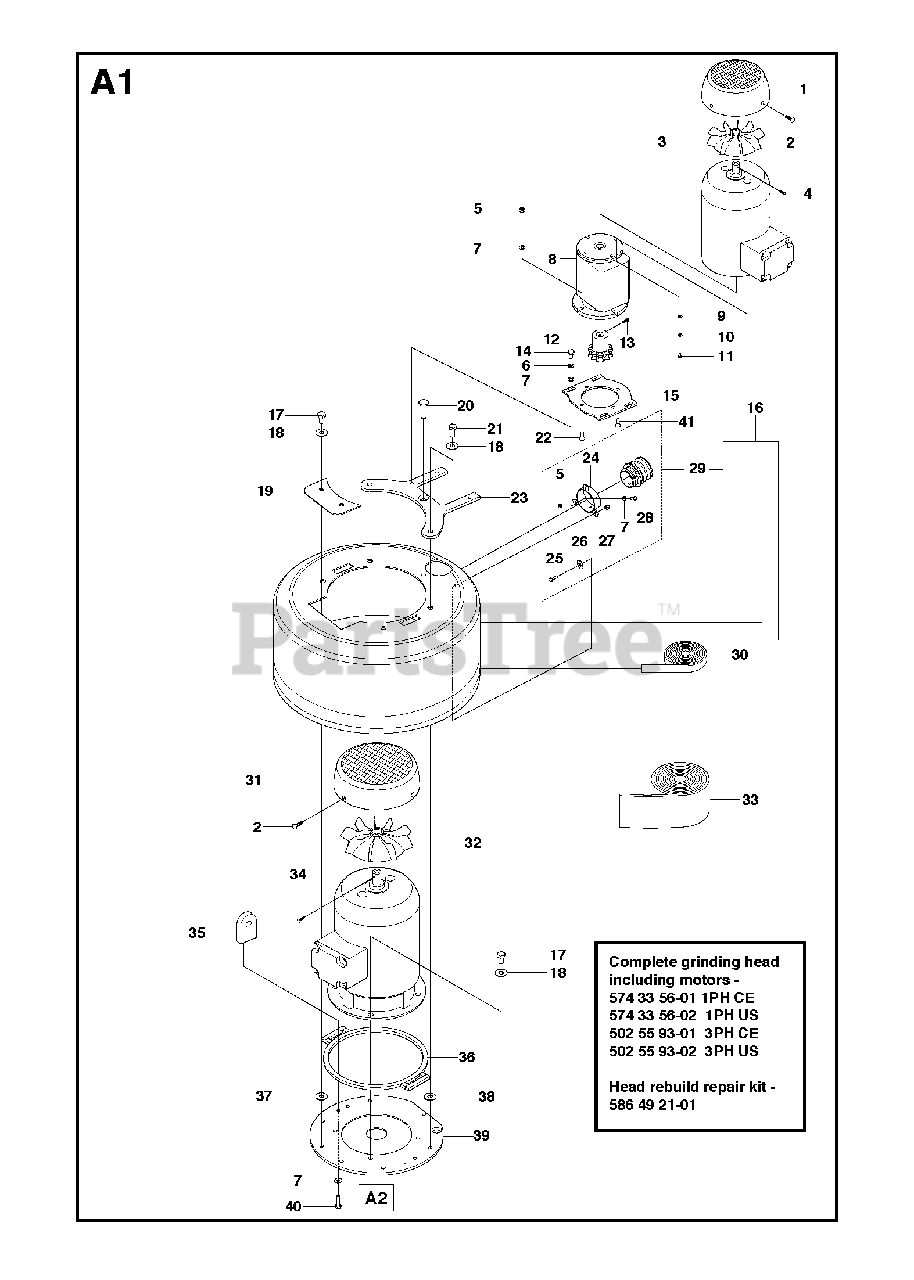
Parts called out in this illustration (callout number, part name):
5	HEXAGON LOCKING NUT
6	SPRING WASHER
7	WASHER
14	SCREW EHHM
18	WASHER
25	SCREW CRCSFM
27	HEXAGON LOCKING NUT
